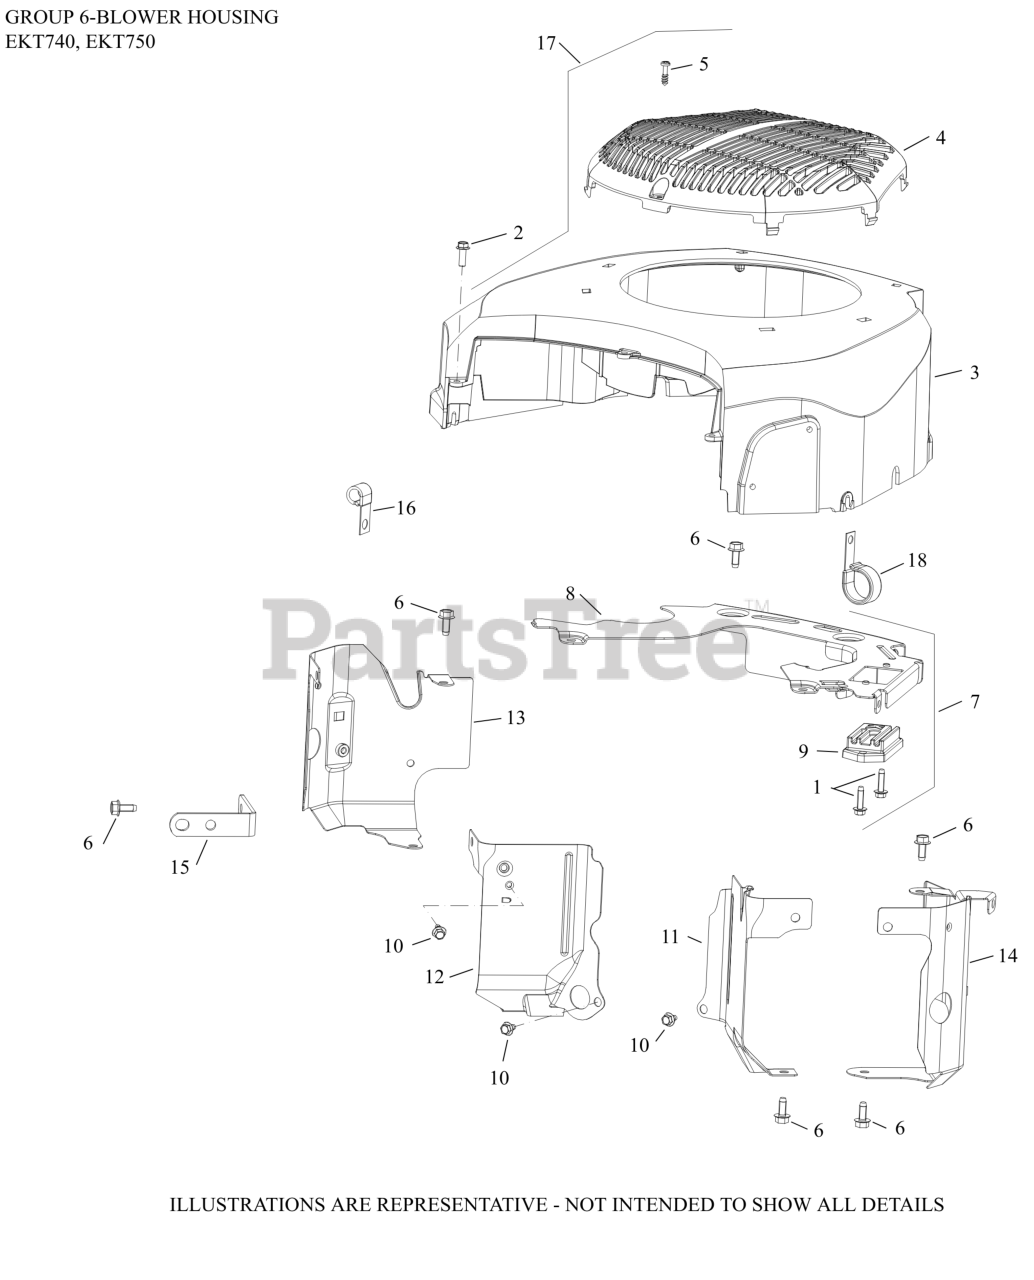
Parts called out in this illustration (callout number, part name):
1	SCREW, THD FRM-USE 25 086 473-S
2	SCREW, HI-LOW
4	GUARD, FIXED
5	SCREW, M5-2.42 (PT) THREAD
6	SCREW, THREAD FORMING
7	PLATE ASSEMBLY, BACKING (15A)
8	PLATE, BACKING
9	REG/RECT (15 AMP, HW, OVP)-(#2540338S)
10	SCREW, THREAD FORMING
11	BAFFLE, VALLEY #2
12	BAFFLE, VALLEY #1
13	BAFFLE, EFI RIGHT BARREL
14	BAFFLE, EFI LEFT BARREL
15	STRAP, LIFTING
17	KIT, BLOWER HOUSING
46	CLIP, CABLE (KM)
